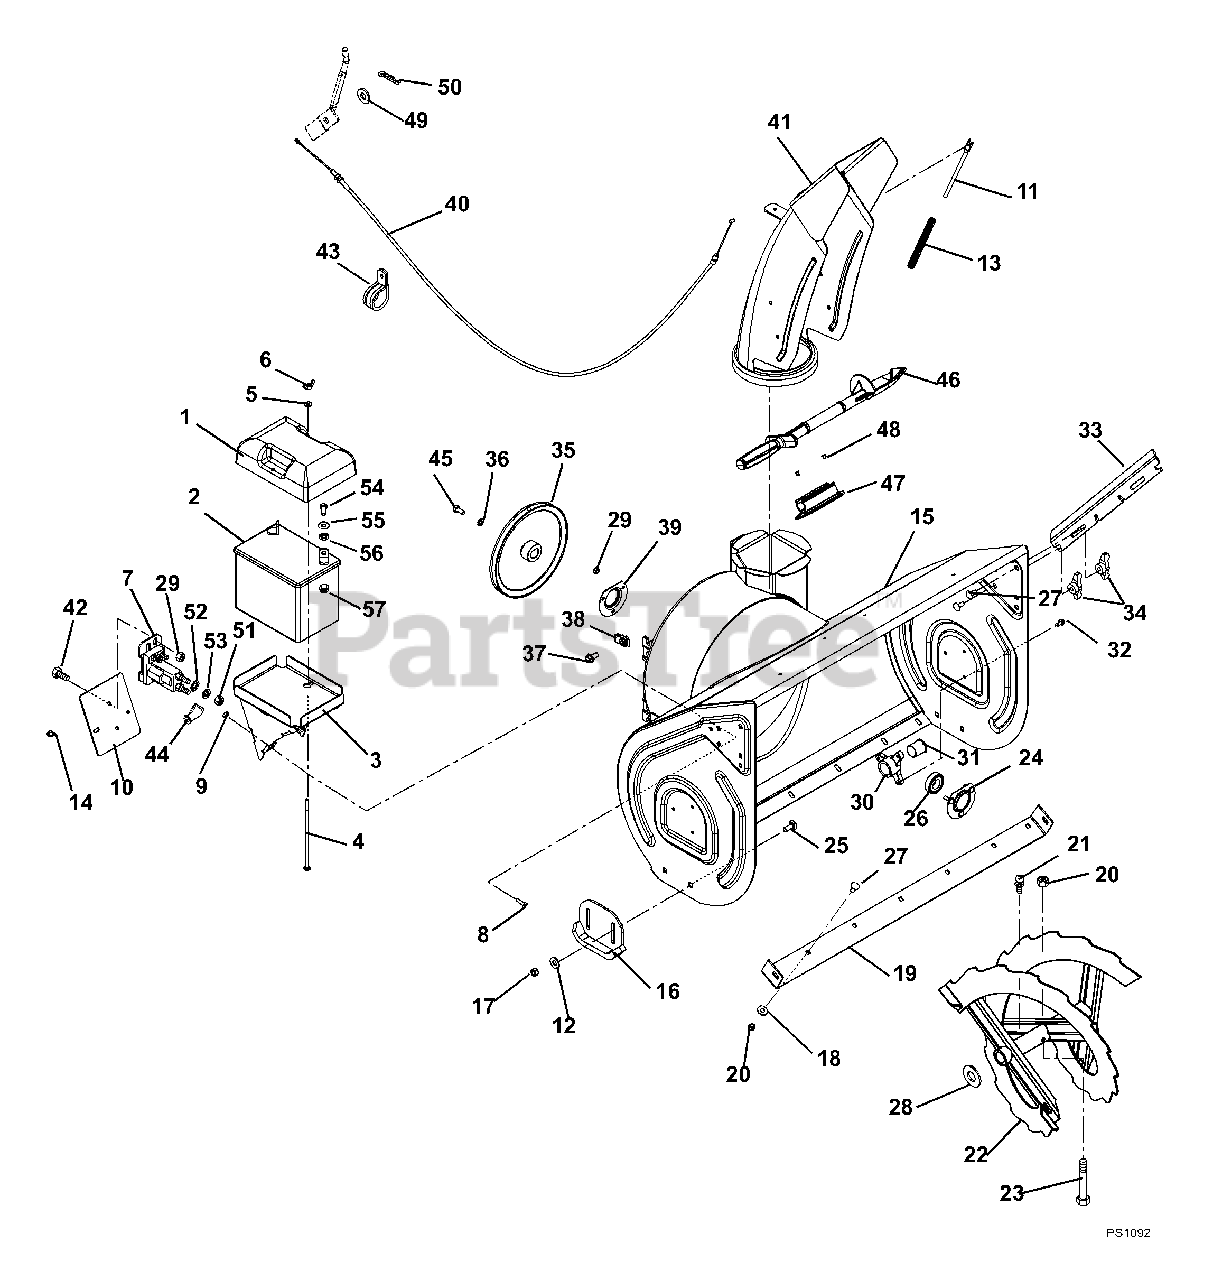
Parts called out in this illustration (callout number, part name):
1	COVER, BATTERY
3	TRAY, BATTERY
4	@BLT-RDHDSQNK .25-20X7.00 G2YZ
5	@WSHR-FL-STL.281X.62X.065 YWZC
6	NUT-LK WING .250-20 YWZC
7	SOLENOID
8	@BLT-HEX .25-20X.75 GR5 YWZC
9	@NUT-SPNLK-FLG .25-20 YWZC
10	COVER, SOLENOID
11	ROD, DEFLECTOR CAP
12	@WSHR-FL-STL.438X1.00X.083 YWZ
13	SG-COMP .08X.40X6.50 14#/IN
14	@SCR-TAP .25-20X.50 HWH TR YWZ
15	HOUSING, BLOWER-26" W/DECAL
15	HOUSING, BLOWER-28" W/DECAL
15	HOUSING, BLOWER-32" W/DECAL
15	HOUSING, BLOWER-32"BAT W/DECAL
15	HOUSING, BLOWER-36" W/DECAL
16	RUNNER, SKID SHOE-1/2" FLANGE
16	SKID SHOE, REVERSIBLE - ORANGE
17	@NUT-LK-CTR .38-16 YWZC
18	@WSHR-FL-STL.438X1.00X.083 YWZ
18	@WSHR-FL-STL.38X.875X.083 YWZC
19	BLADE, SCRAPER-26"
19	BLADE, SCRAPER-28"
19	BLADE, SCRAPER-32"
19	BLADE, SCRAPER-36"
20	@NUT-LK-CTR .31-18 YWZC
21	FTG-LUBE .25-28X.256 YWZC
22	RAKE, LH-26"(1 ID X 15.75 OD)
22	RAKE, RH-26" (1 ID X 15.75 OD)
22	RAKE, LH-28" (1 ID X 15.75 OD)
22	RAKE, RH-28" (1 ID X 15.75 OD)
22	RAKE, LH-32" (1 ID X 15.75 OD)
22	RAKE, RH-32" (1 ID X 15.75 OD)
22	RAKE, LH-36" (1ID X 15.75 OD)
22	RAKE, RH-36" (1 ID X 15.75 OD)
23	SHEAR BOLT SERVICE ASSEMBLY
24	BEARING FLANGE
25	@BLT-RDHDSHSQNK.38-16X1.0 G5YZ
26	BRG-BALL .876 X 1.750 X .50
27	@BLT-RHDSSQNK .31-18X.75 G5YZ
28	WSHR-FL-STL 1.010X1.505X.062YZ
29	@NUT-LK-CTR .25-20 YWZC
30	BUSHING, RAKE SHAFT 1"
31	BSHG-FLG, SPLIT NYLINER 1.0"ID
32	@SCR-TAP .25-20X.50 HWH TR YWZ
33	CUTTER, DRIFT
34	KNOB - WING .312-18 UNC
35	PULLEY, 4L W/HUB, .87 X 8.5
36	WSHR-LK .312X.097 HVY YWZC
37	BLT-SERHFWH .38-16X.75 YWZC
38	NUT-RTNR .375-16X.37
39	BEARING FLANGE
40	CABLE, DEFLECTOR
41	CHUTE, DISCHARGE-W/DEFLECTOR
42	@BLT-HEX .25-20X.50 GR5 YWZC
43	CLAMP, CUSHIONED STEEL
44	BOOT, EYELET TERMINAL
45	BLT-HEX .31-24X.75 YWZC GR5
46	DEVICE, SNOW CLEAN OUT
47	MOUNT, SNOW CLEAN OUT
48	RVT-POP .187X.45 DOME SS FBF64
49	@WSHR-FL-STL.281X.62X.065 YWZC
50	PIN-HAIR INT .06X.18X.77
51	NUT-JAM .31-24 YWZC
52	WSHR-LOCK INT .31 YWZC
53	@WSHR-LK .31X.078 REG YWZC
54	@BLT-HEX .25-20X.75 GR5 YWZC
55	WSHR-FL-STL .265X.50X.087YWZC
56	@WSHR-LK .25X.062 REG YWZC
57	@NUT-HEX .25-20 YWZC
